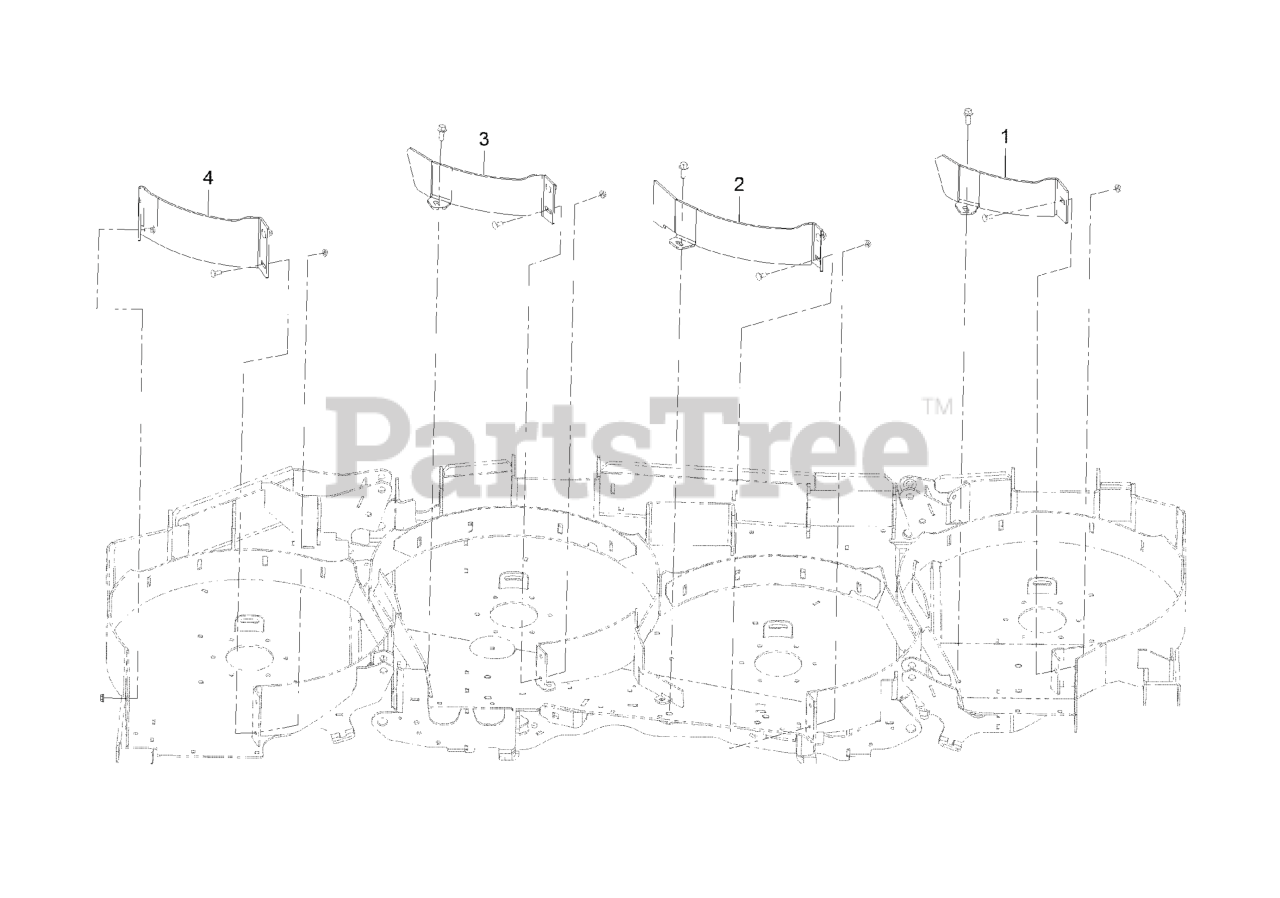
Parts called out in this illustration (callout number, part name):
1	BAFFLE-BLOCK, LH WING
2	BAFFLE-BLOCK, LH CTR
3	BAFFLE-BLOCK, RH CTR
4	BAFFLE-BLOCK, RH WING
